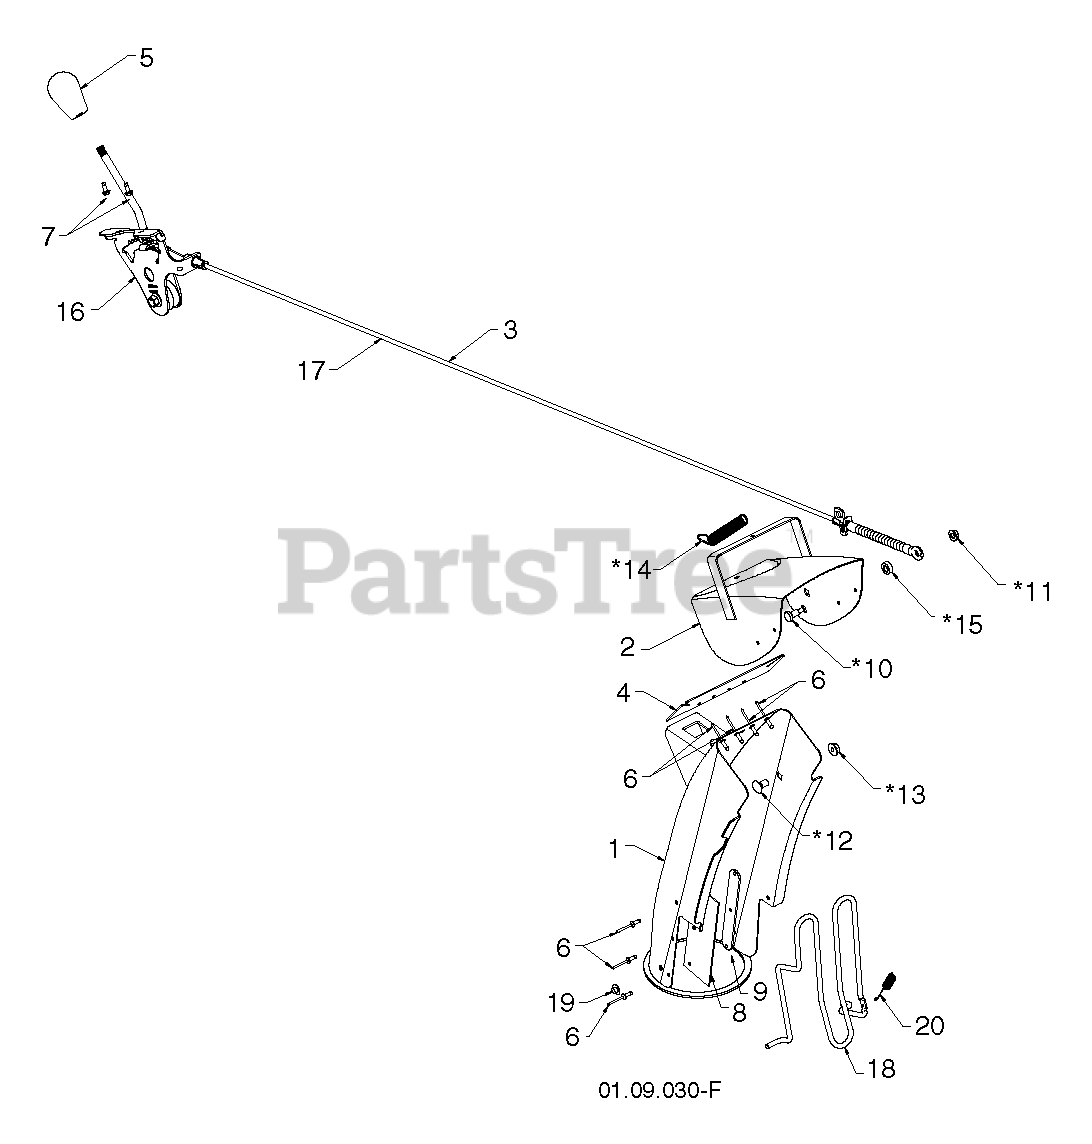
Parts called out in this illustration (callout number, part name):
1	ASM.CHUTE/DEFLECTOR.668
3	CONTROL.ASM.DEFLEC.BLK.BOWDEN
5	KNOB.OVERMOLD.DS.HUSQVARNA/BLK
10	BOLT.CARR.W.3125 SHLDR..25-20
11	NUT.HEX.FLANGE.1/4
12	BOLT CAR BLK 5/16-18 X 5/8
13	LOCKNUT-FLANGE 5/16-18
14	SPRING.DEFLECTOR.REM.CHUTE
15	WASHER.NYLON.326 X.625 X.205
16	RP CNTRL.HEAD.ASSEM.DEFLECTOR
17	RP CABLE.DEFLECTOR.CONTRL.BOWD
18	ROD.GUARD.CHUTE (2 2)
19	NUT
20	SPRING.CHUTE.GUARD
